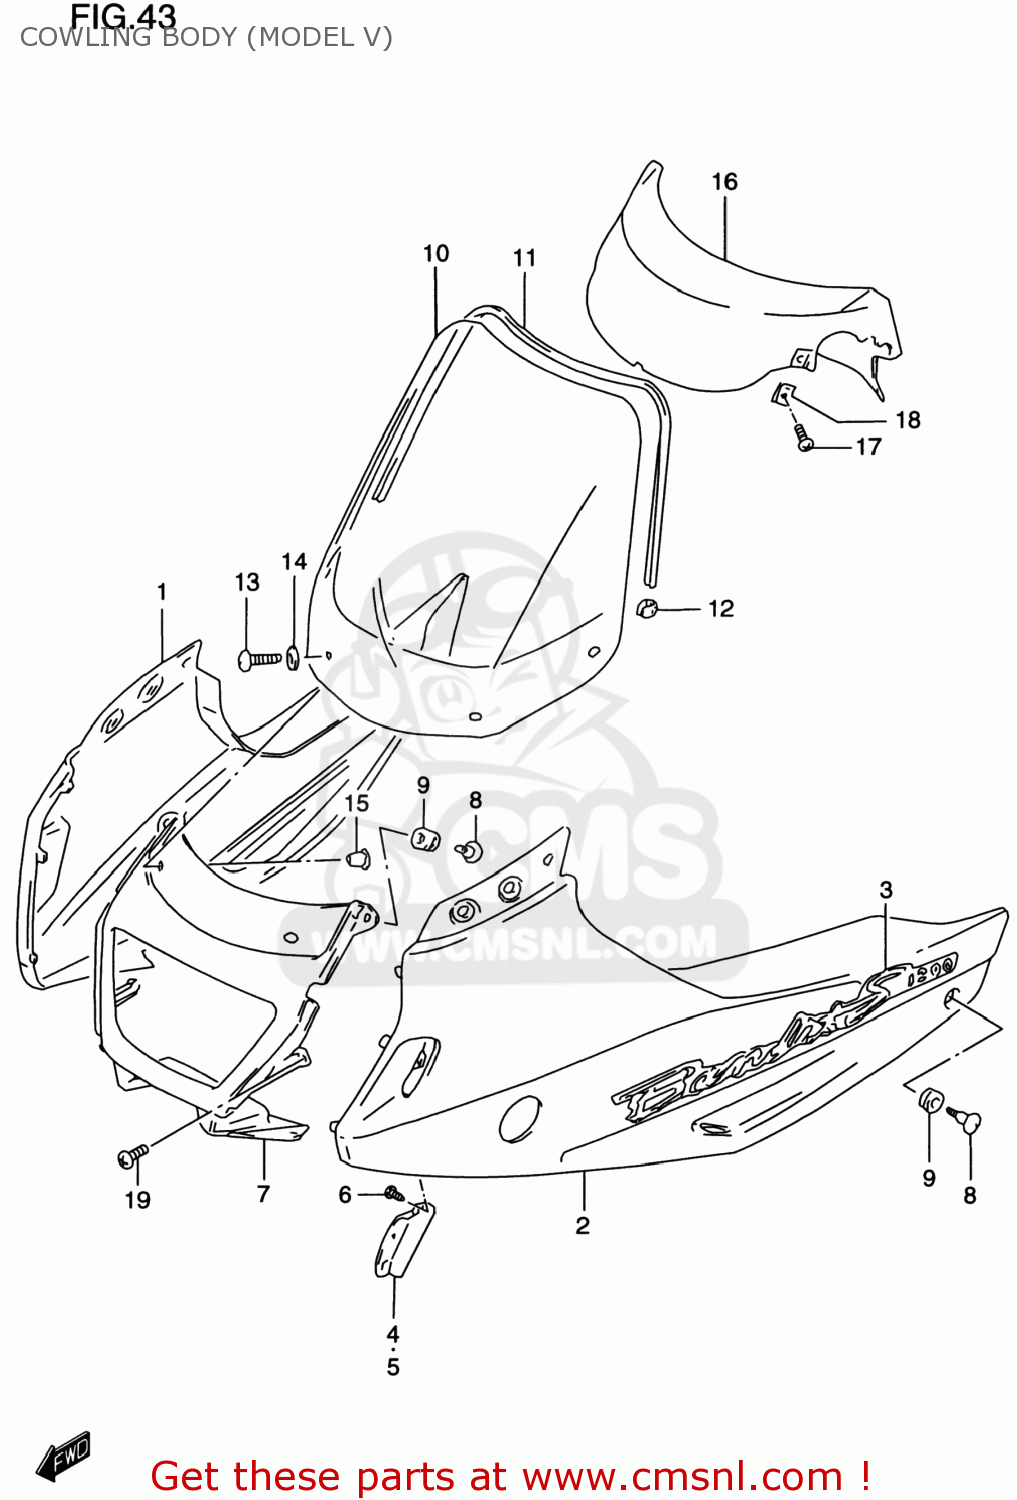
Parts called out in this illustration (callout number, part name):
1	COWLING ASSY,SIDE,R
2	COWLING ASSY,SIDE,L
3	EMBLEM,COWLING SIDE
4	COVER,COWLING INNER,R
5	COVER,COWLING INNER,L
6	SCREW 5X10
7	COWLING ASSY,CTR
8	SCREW(6X20)
9	CUSHION
10	WINDSCREEN SET
11	MOLDING WINDSCREEN
12	CLIP,WINDSCREEN MOLDING
13	SCREW(5X14)
14	WASHER
15	NUT
16	PANEL,INNER
17	SCREW
18	NUT
19	SCREW
